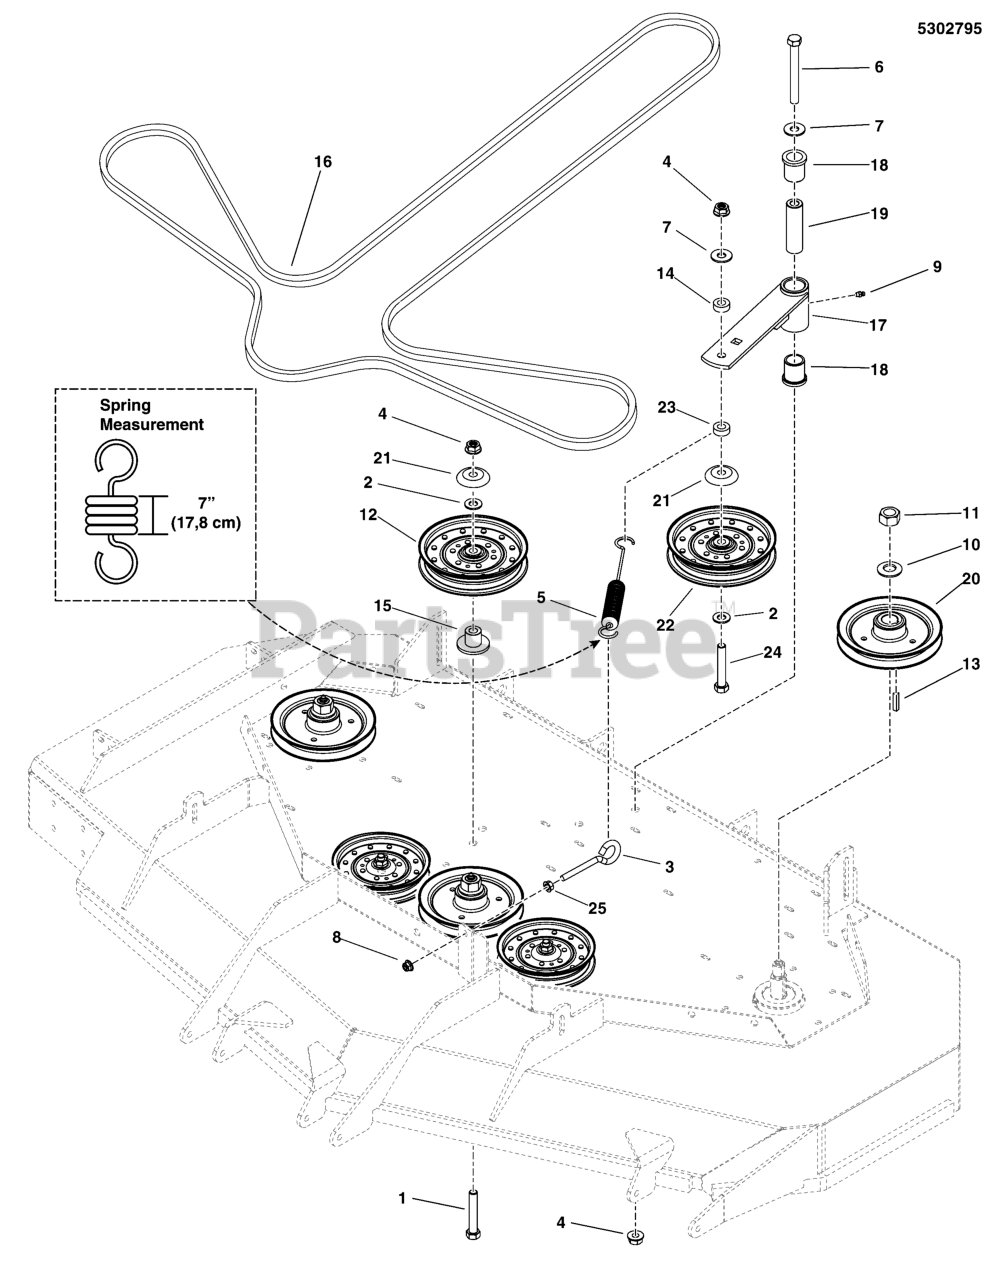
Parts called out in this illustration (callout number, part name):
1	BOLT, 1/2-13 X 3" GD5 CZ
2	WASHER, 1/2 SAE
3	EYE BOLT, 3/8-16 X 2-1/2
4	NUT, Hex Flange, Nylock, 1/2-13
5	SPRING, EXTENSION, SWIVEL END
6	BOLT, 1/2-13 X 4-1/2 GD5
7	WASHER, 1/2 USS
8	NUT, 3/8-16 HEX NYLOCK FLANGE
9	GREASE FITTING, 1/4-28 STRAIGHT
10	WASHER, 3/4 BELLEVILLE
11	NUT, 3/4-16 HEX
13	KEY, 1/4 SQ. X 1-1/4
14	SPACER, .52 X 1.00 X .38
15	IDLER MOUNT
16	BELT, 5V, 172.75"EL, LG ARAMID WRPD, RC
17	WELD, IDLER ARM - BLK
18	BUSHING, FLANGE
19	SPACER, .52 X 1.00 X 3.50
20	PULLEY, SPIN, 6.5 OD X 25MM,
21	SHIELD, PULLEY BEARING
23	SPACER, .52 X 1.00 X .88
24	BOLT, 1/2-13 X 3-1/4, HEX HD, GD5, CZ (SV)
25	NUT, 3/8-16 HEX JAM
